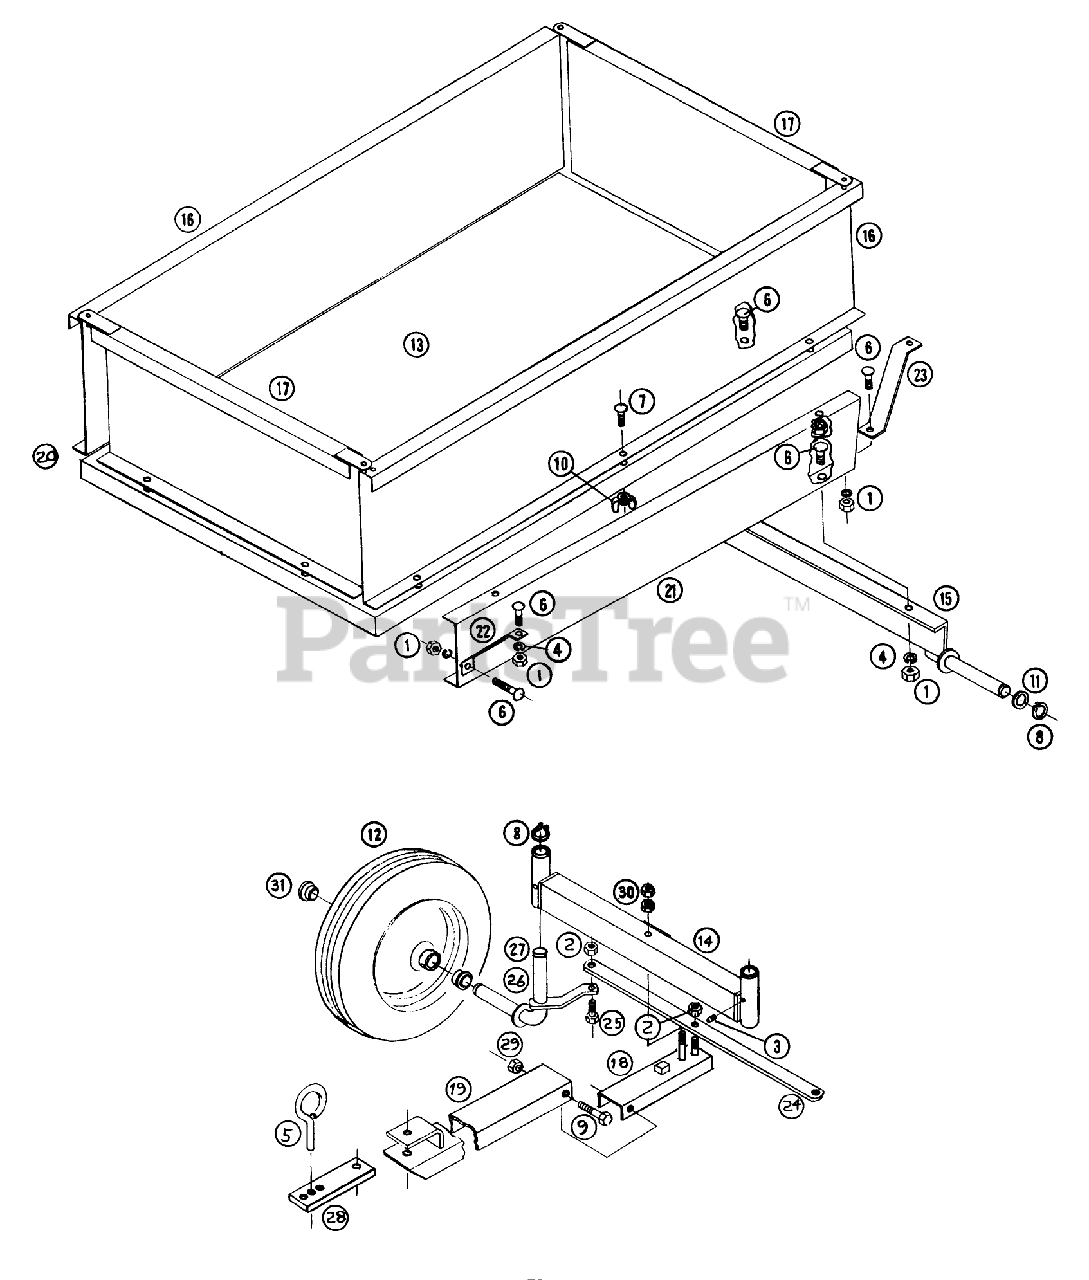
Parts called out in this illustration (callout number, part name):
2	Nut-1/2-13
4	Lockwasher
6	Bolt 3/8-16 x 3/4
7	Bolt Hex 3/8-16
8	Snap Ring
9	H.H.C.S. 1/2-13 x 2 1/2
10	3/8 NC Wing Nut
11	WASHER
13	Bed
14	Front Axle Assembly
17	End Panel
19	Draw Bar Assembly
20	Clip
21	Bed Support L.H.
22	Front Brace
23	Rear Brace
25	Clevis Pin
29	Locknut-1/2-13
30	Hex Jam Nut 5/8-11
